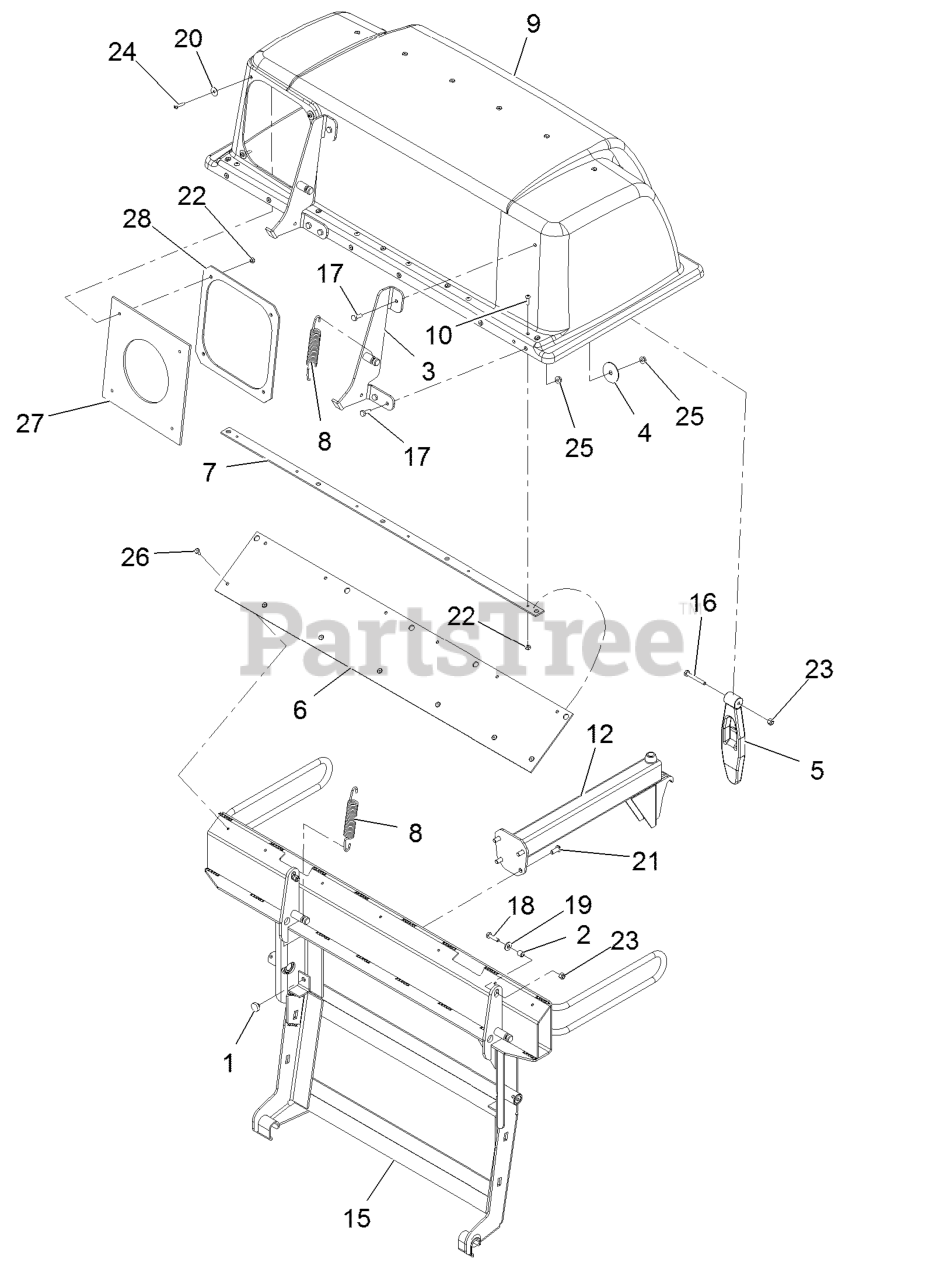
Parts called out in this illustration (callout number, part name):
3	Hinge ASM
7	Plate-Backing
8	Spring-Extension
9	Hood Assembly - Service Only
10	Screw-Truss Head #10-24 X 3/4
12	Bag Support ASM
15	Frame-Bag, Twin
16	Screw-HH 1/4-20 X 2
17	Screw-HH 1/4-20 X 3/4
18	Screw-HH 1/4-20 X 1
19	Washer-1/4 Std
21	Screw-Button Head 5/16-18 X 3/4
22	Nut-Nyloc #10-24
23	Nut-Nyloc 1/4-20
24	Screw-PPH #10-24 X 7/8
25	Nut-Whizlock 1/4-20
27	Seal-Chute
28	Clamp-Seal
